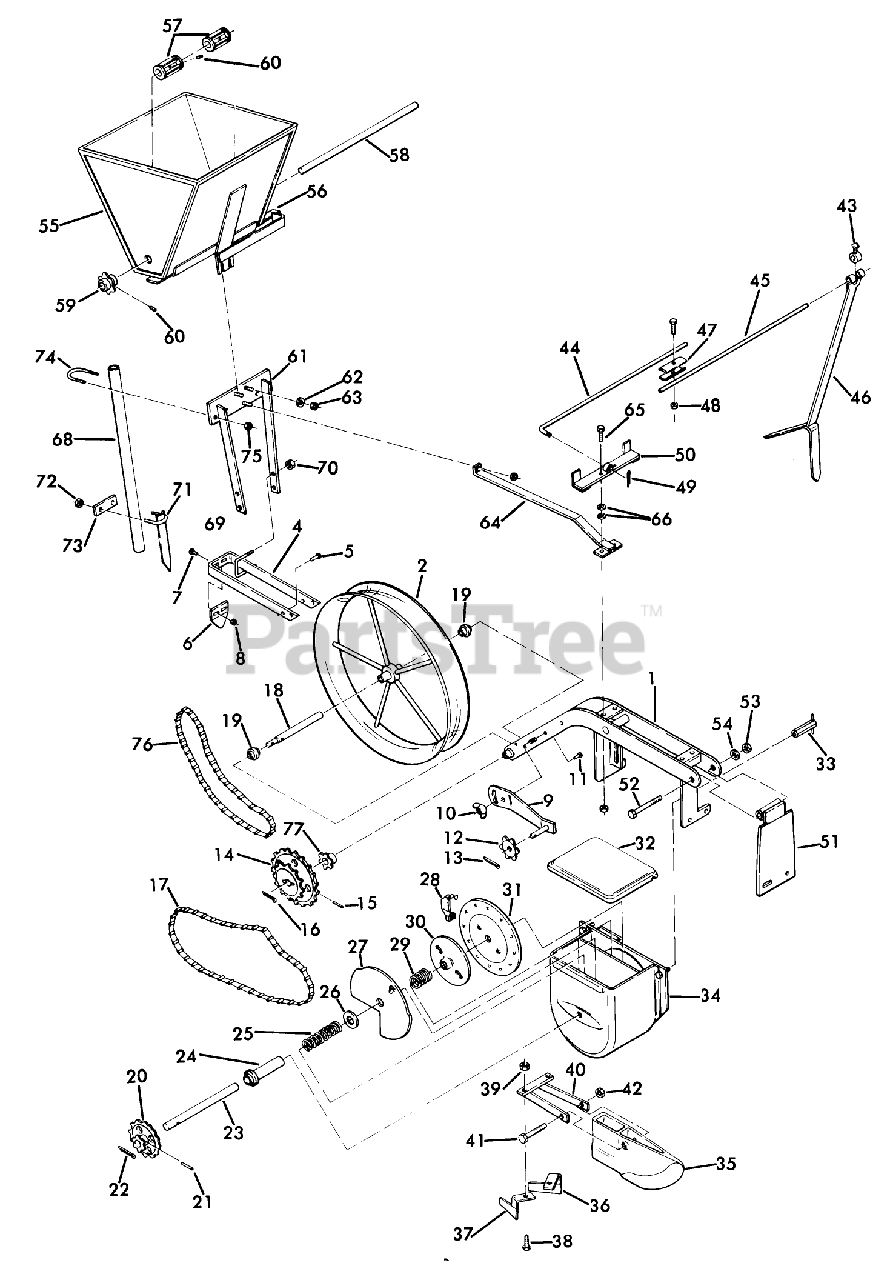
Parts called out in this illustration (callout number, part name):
1	Chassis Assembly
2	Sq. Hd. Set Screw (Cup Pt.) 1/4-20 x 1 1/4
5	Rivet 1/4 x 3/8
10	WING NUT
11	Rivet 1/4 x 3/8
15	PIN-SPIROL
21	PIN-SPIROL
31	12 Pocket Seed Disc (1/8" Seed Pocket)
